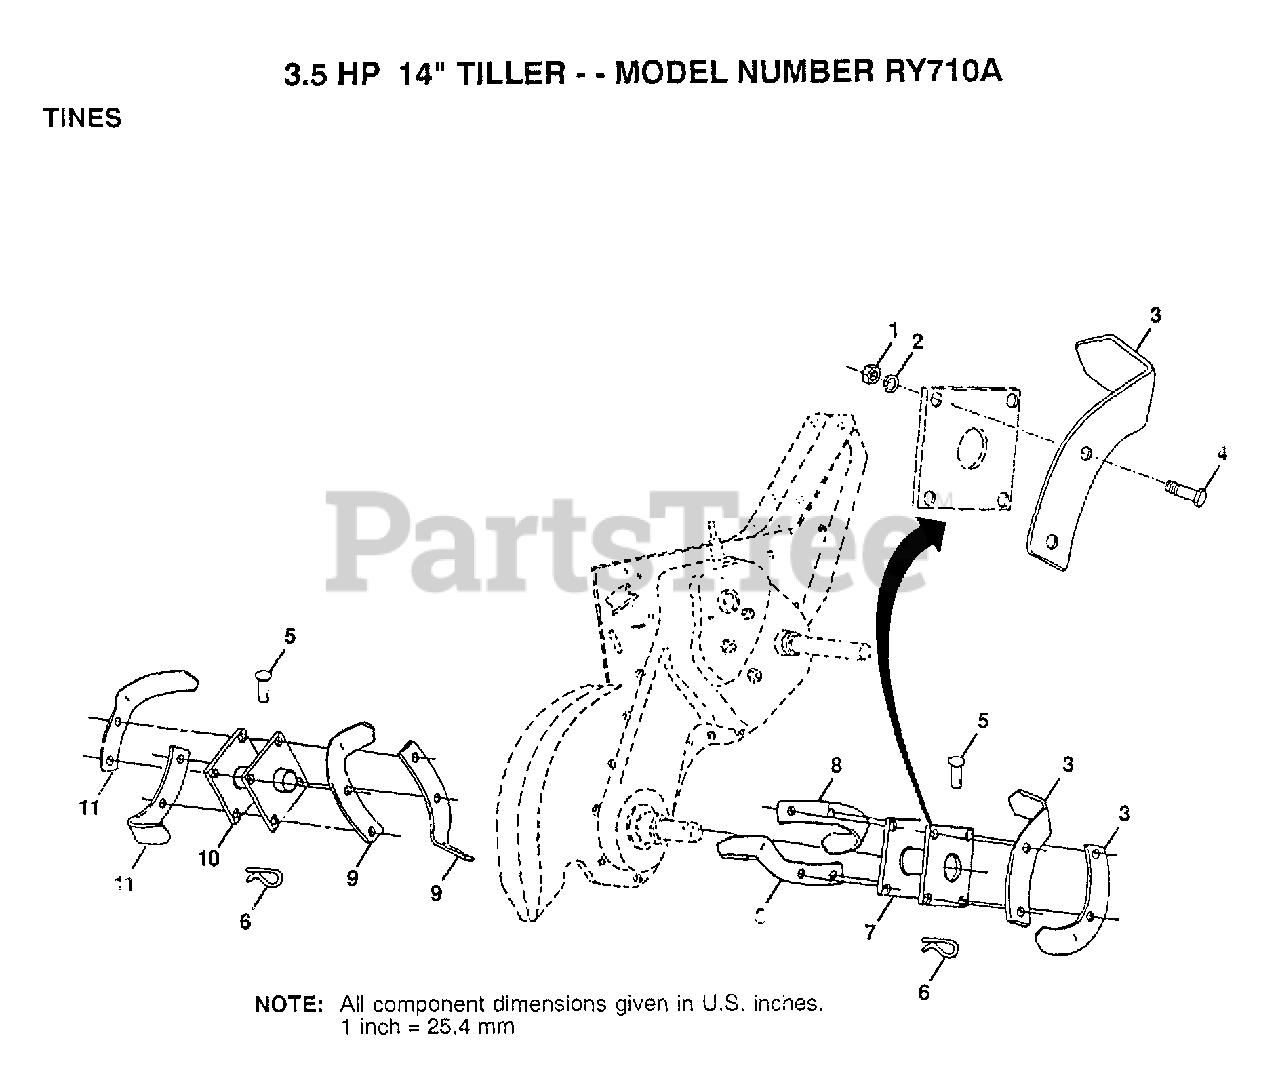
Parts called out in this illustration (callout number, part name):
2	LOCKWASHER
4	BOLT
5	PIN.CLEVIS.SHEAR
6	RETAINER.SPRING
7	ASM HUB&PLATE RH
8	"TINE.RH.12"""
9	"TINE.LH.12"""
10	ASM HUB&PLATE LH
